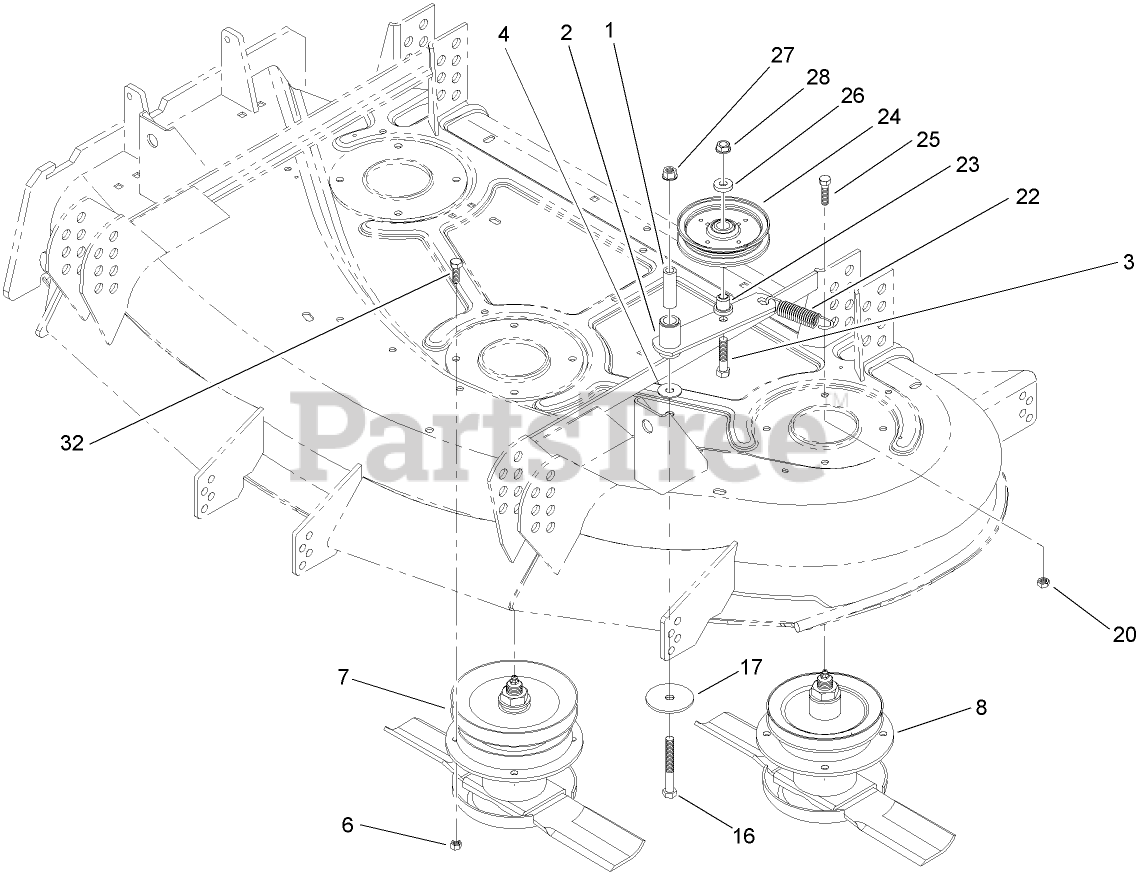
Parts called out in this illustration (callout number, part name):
1	SPACER
2	IDLER ARM ASM
3	SCREW-HH
4	WASHER
6	NUT-LOCK, CONE
7	Spindle Housing ASM
8	SPINDLE HOUSING ASM
16	SCREW-HH
17	WASHER-END
20	NUT-JAM
22	Spring-Extension
23	BUSHING-PULLEY
24	PULLEY-IDLER
25	SCREW-HH
26	WASHER-FLAT
27	NUT-HF
28	NUT-HEX
32	SCREW-HH
